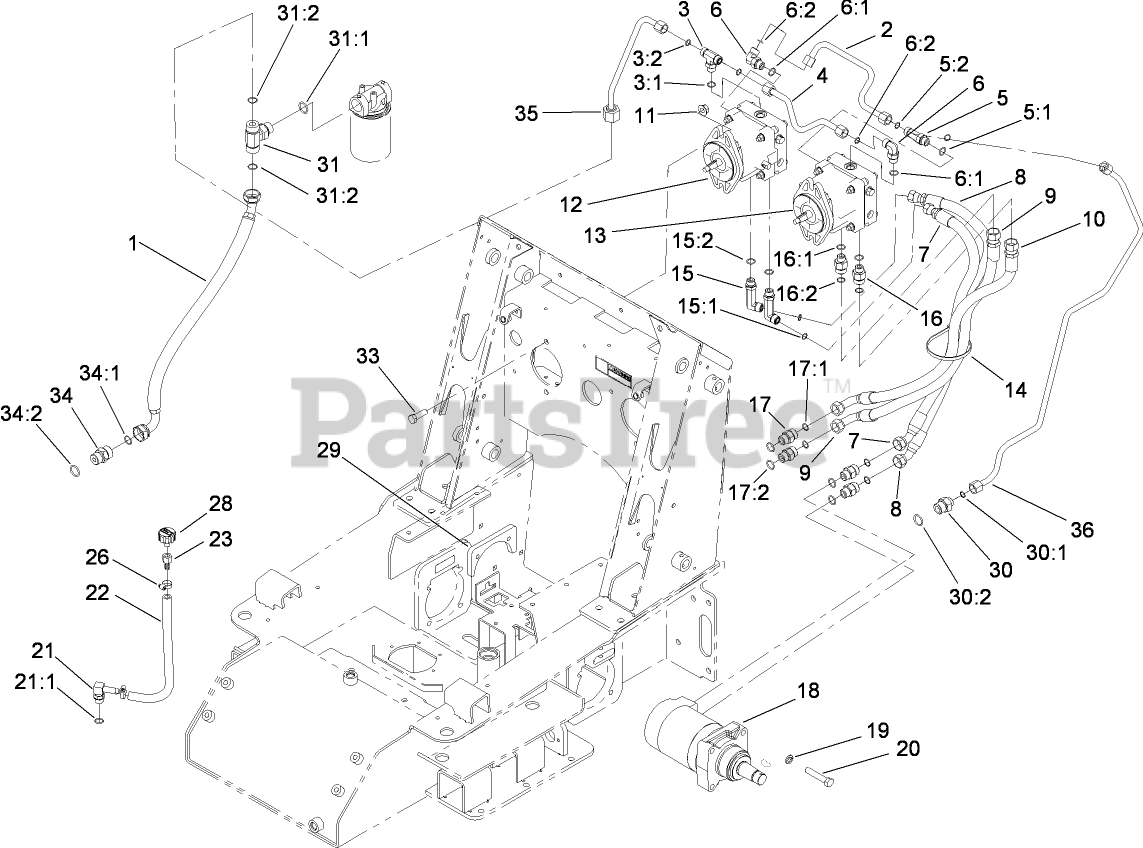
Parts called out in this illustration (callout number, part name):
1	HYD HOSE ASM
2	TUBE-HYD
3	FITTING-HYD, TEE
3:1	O-RING
3:2	O-RING
4	TUBE-HYD
5	FITTING-TEE
5:1	O-RING
5:2	O-RING
6	FITTING-ELBOW-90 DEG
6:1	O-RING
6:2	O-RING
7	HYD HOSE ASM
8	HYD HOSE ASM
9	HYD HOSE ASM
10	HYD HOSE ASM
11	NUT-LOCK, FLANGE
12	PUMP-HYD, RH
13	PUMP-HYD, LH
14	TIE-CABLE
15	FITTING-ELBOW, 90 DEG
15:1	O-RING
15:2	O-RING
16	FITTING-STR
16:1	O-RING
16:2	O-RING
17	FITTING-STRAIGHT
17:1	O-RING
17:2	O-RING
18	HYD MOTOR ASM
19	WASHER-LOCK
20	SCREW-HH
21	FITTING-ELB 90
21:1	O-RING
22	HOSE-DRAIN, OIL
23	FITTING-FEMALE, BARBED
26	CLAMP-HOSE
28	BREATHER
29	PLATE-MOUNTING
30	FITTING-STR
30:1	O-RING
30:2	O-RING
31	FITTING-TEE
31:1	O-RING
31:2	O-RING
33	SCREW-HH
34	VALVE-CHECK, HYD
34:1	O-RING
34:2	O-RING
35	HYD TUBE ASM
36	HYD TUBE ASM
